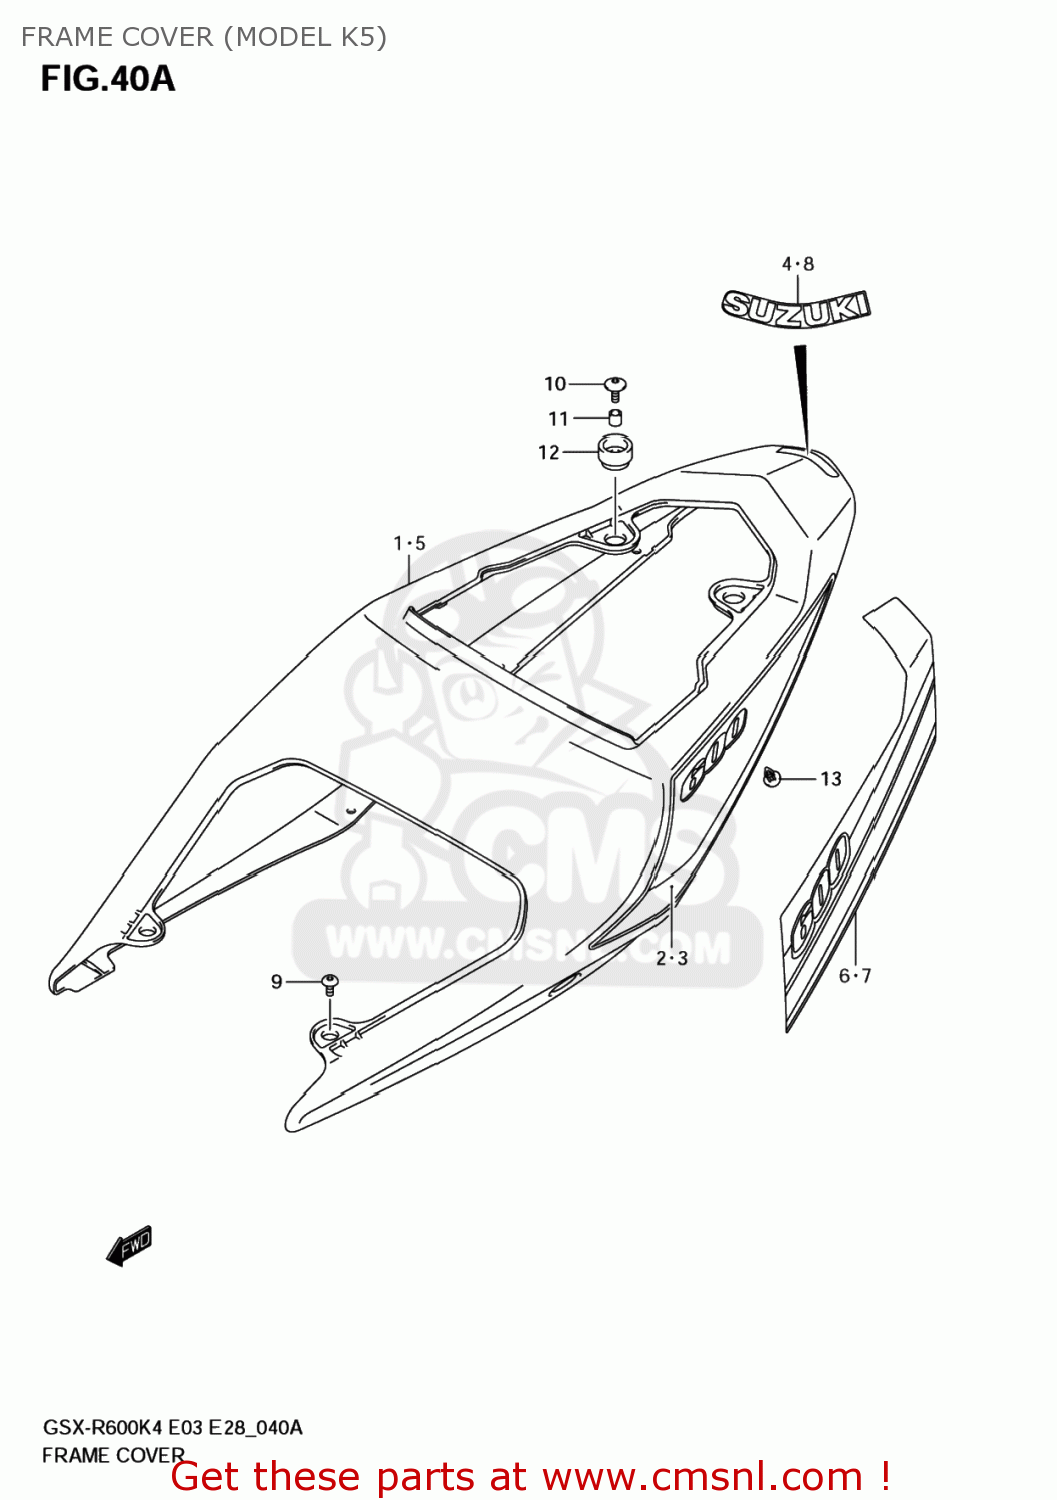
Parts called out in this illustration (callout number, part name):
1	COVER ASSY,FRAME(RED)
2	TAPE,FRAME COVER,R
3	TAPE,FRAME COVER,L
4	EMBLEM,SUZUKI
5	COVER ASSY,FRAME(BLUE)
6	TAPE,FRAME COVER,R
7	TAPE,FRAME COVER,L
8	EMBLEM,SUZUKI
9	SCREW(6X16)
10	SCREW(6X16)
11	SPACER(6.5X10X9.4)
12	CUSHION
13	CLIP(BLACK)
